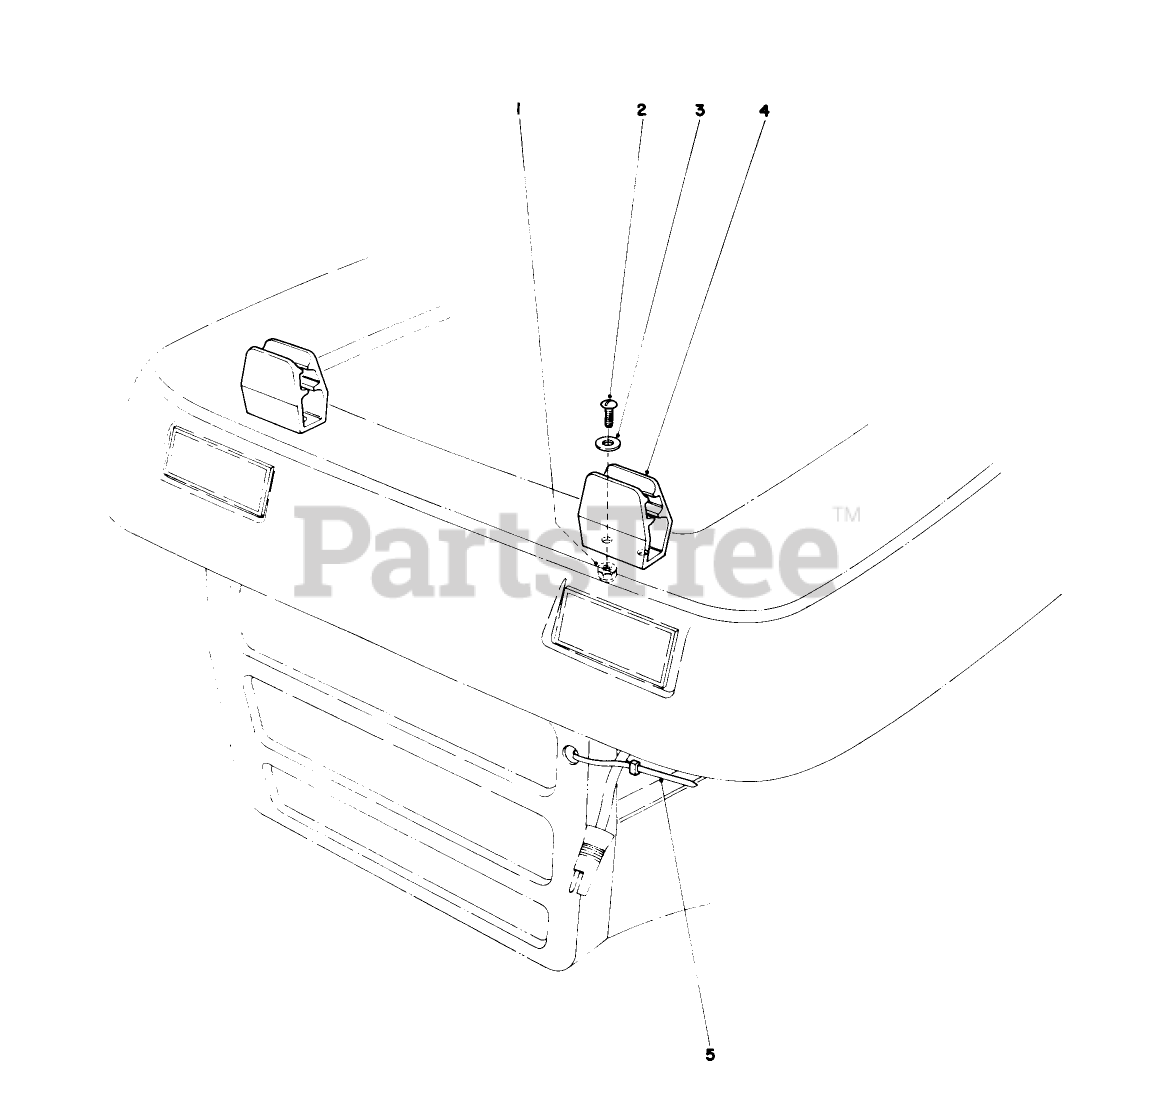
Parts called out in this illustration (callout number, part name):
1	NUT-LOCK, NI
2	SCREW
3	WASHER-FLAT
5	TIE-CABLE
